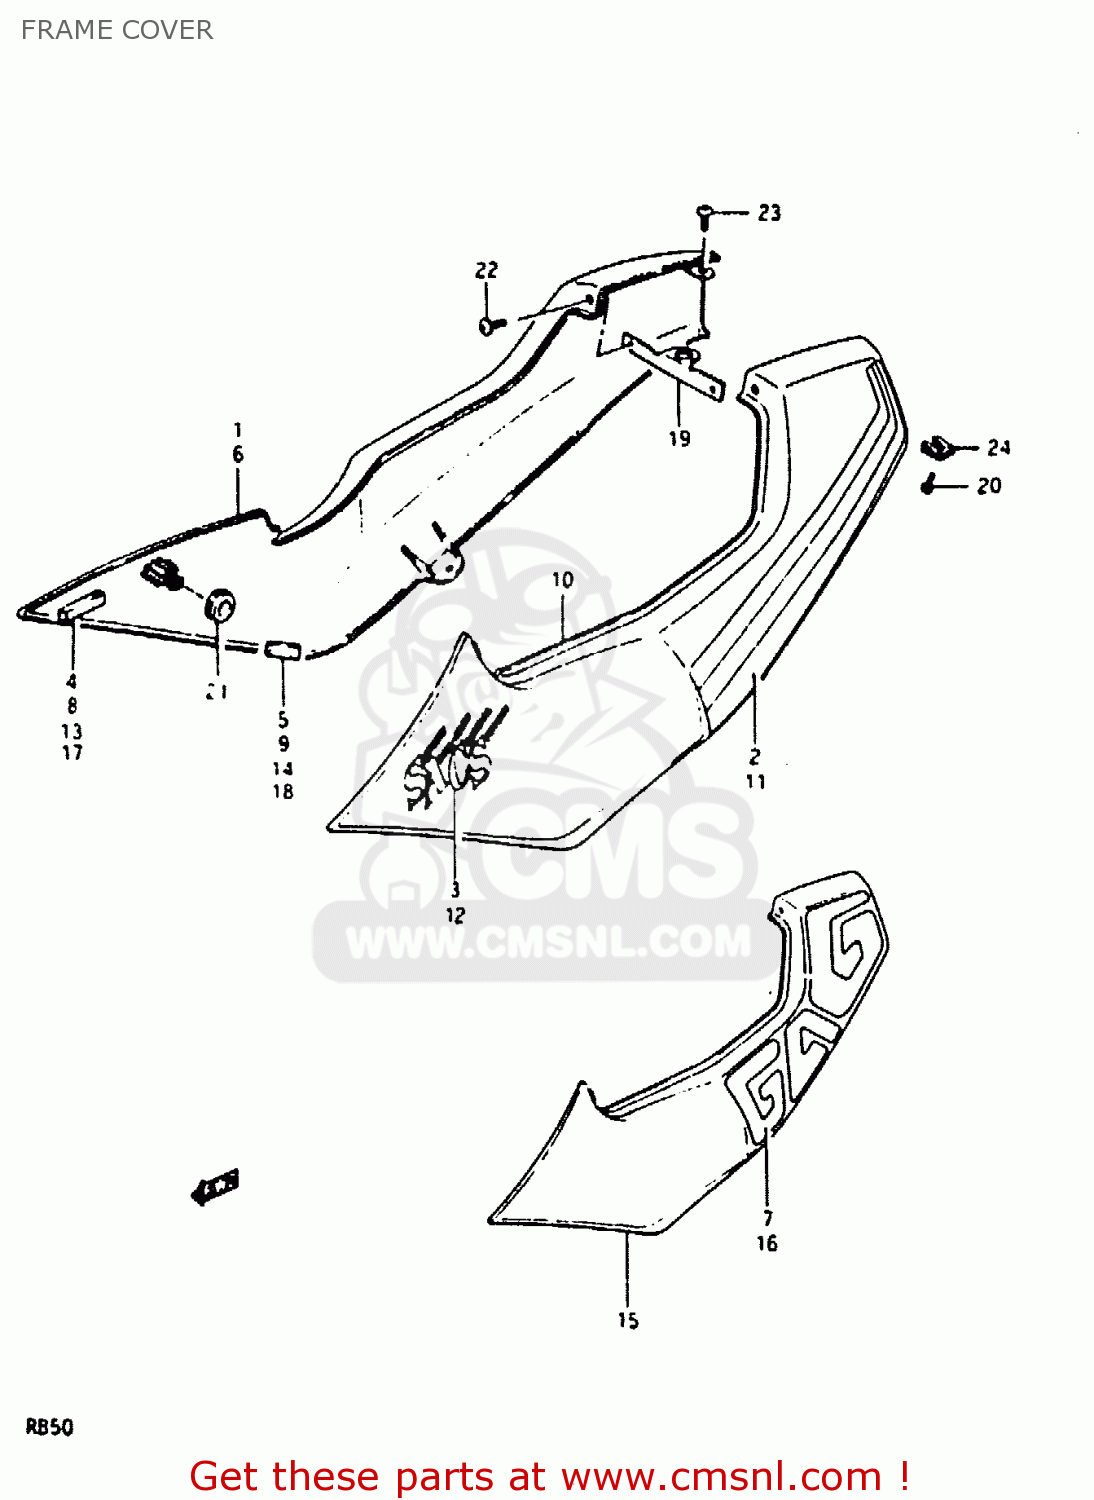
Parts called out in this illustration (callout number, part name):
1	COVER,FRAME,R
2	TAPE SET,SIDE COVER,RIGHT
3	ZIJDEKSELEMBLEM
4	CUSHION,FR
5	CUSHION,REAR
6	COVER,FRAME,R
8	CUSHION,FR
9	CUSHION,REAR
10	COVER SET,SIDE,L
11	TAPE SET,SIDE COVER,LEFT
12	ZIJDEKSELEMBLEM
13	CUSHION,FR
14	CUSHION,REAR
15	COVER SET,SIDE,L
17	CUSHION,FR
18	CUSHION,REAR
19	BRACKET,SIDE COVER
20	SCREW, FRONT & REAR
21	CUSHION
22	SCREW
23	SCREW
24	NUT
